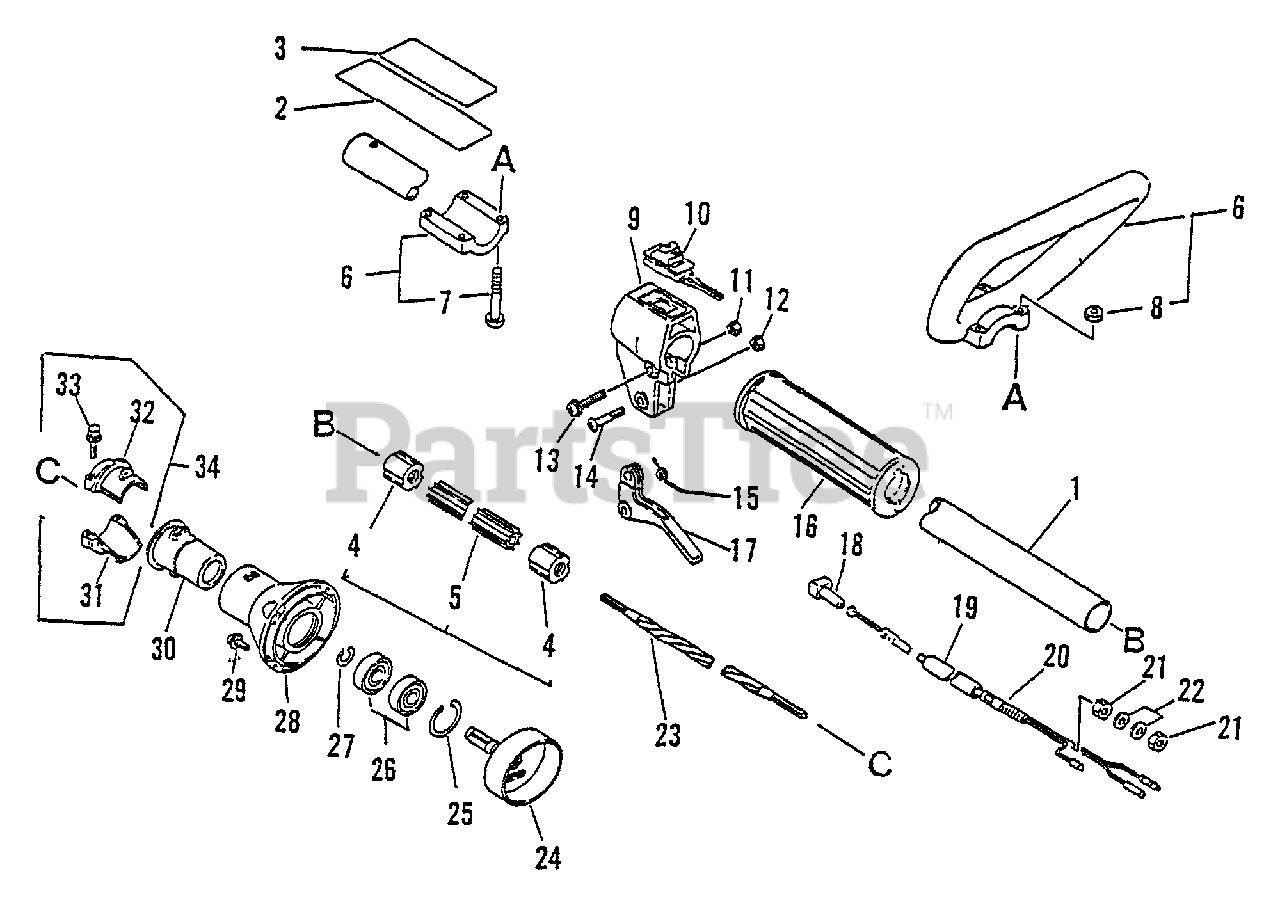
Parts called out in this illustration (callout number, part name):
1	MAIN PIPE ASSY
2	LABEL - CAUTION
3	LABEL - CAUTION
5	LINER - FLEXIBLE
6	LOOP HANDLE ASSY
8	SCREW - 5X35
9	BRACKET, THROTTLE CONTROL
10	IGNITION SWITCH ASSY
12	LOCKNUT - 5
13	SCREW - 5X30
14	SCREW - 5X30
15	SPRING, TRIGGER
16	GRIP, HANDLE
17	TRIGGER, THROTTLE
18	GUIDE, CABLE
19	TUBE - VINYL
20	CABLE, THROTTLE
22	WASHER - 6
23	DRIVESHAFT - FLEXIBLE
24	DRUM, CLUTCH
25	RING, RETAINING - 28
26	BEARING, BALL - 6001
27	RING, RETAINING - 12
28	CASE, CLUTCH - GRAY
29	SCREW - 5X16
31	CLAMP, MAIN PIPE
32	CLAMP, MAIN PIPE - UPPER
33	BOLT - 5X25
